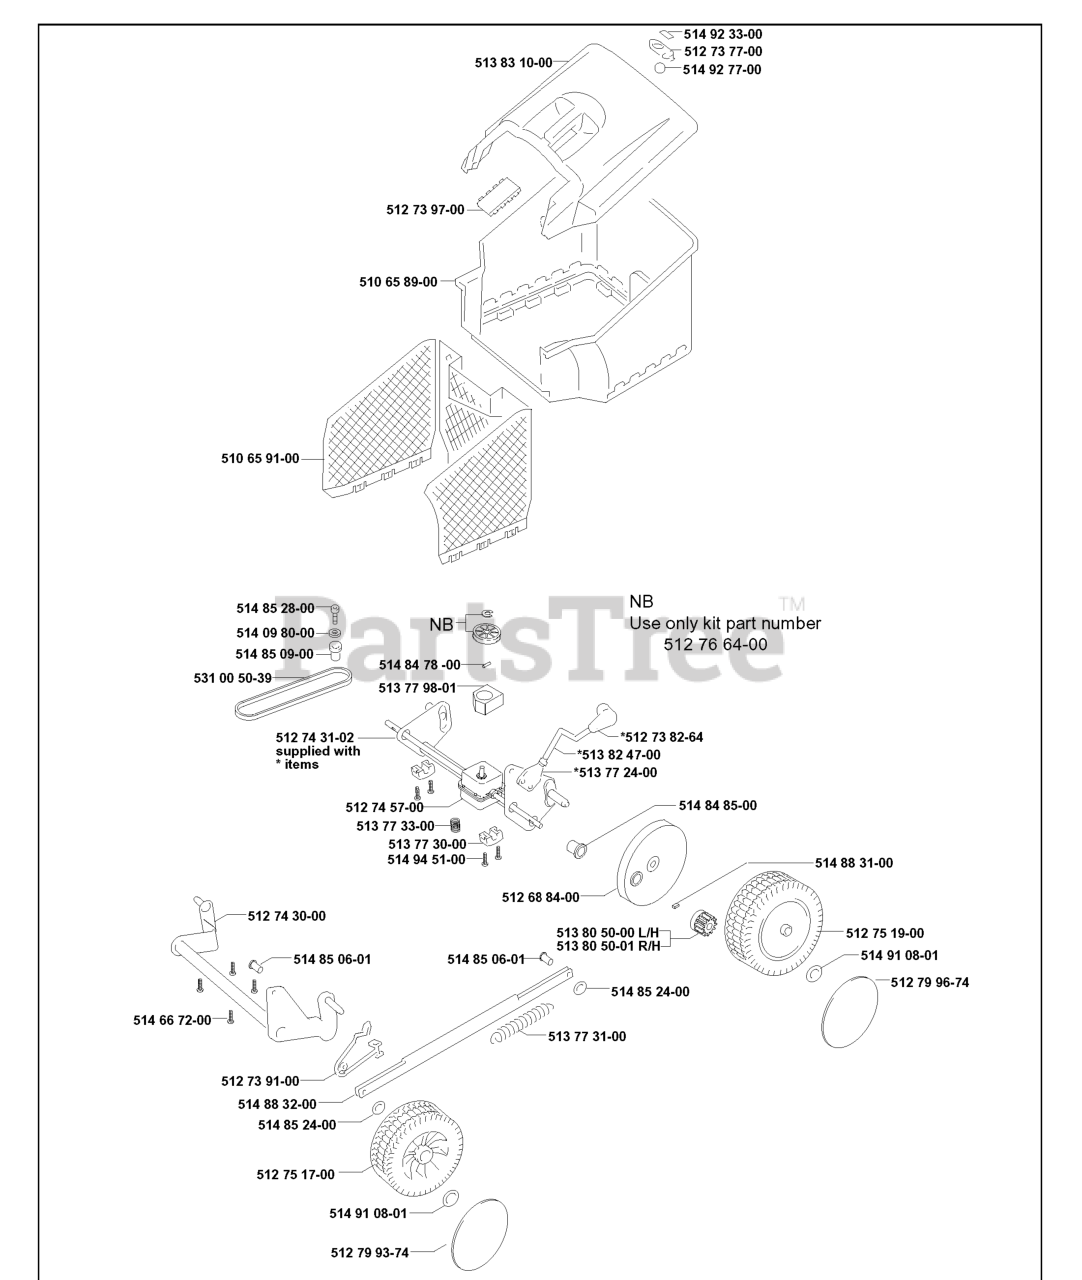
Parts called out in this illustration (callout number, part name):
11	LOCKNUT M6
12	LOCKNUT M5
51	LOCKNUT M6
